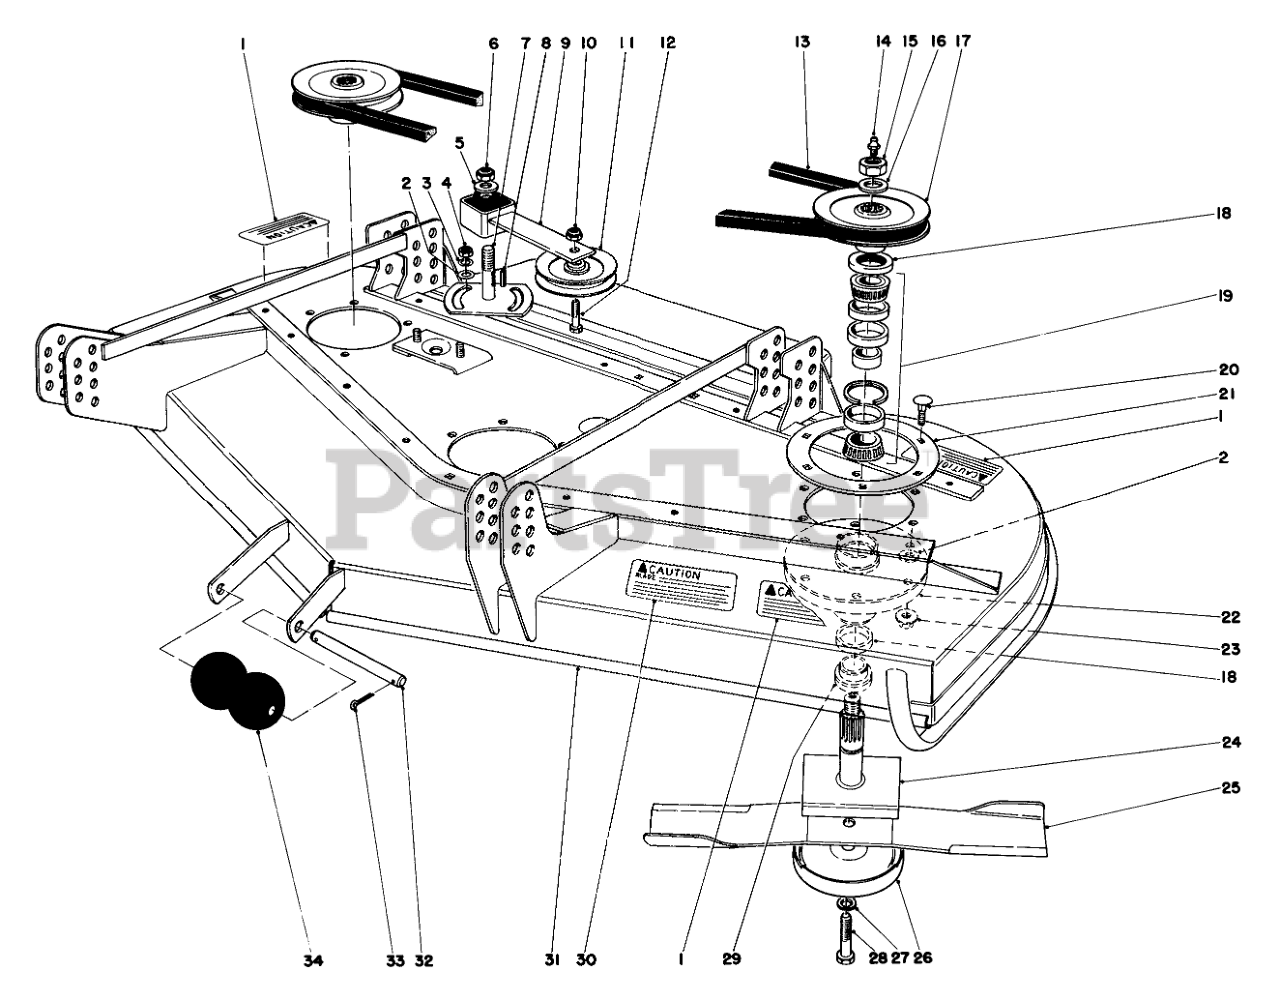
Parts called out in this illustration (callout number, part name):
1	DECAL-CAUTION, BLADE
2	WASHER-FLAT
3	WASHER-LOCK
4	NUT-JAM
5	WASHER-FLAT
6	NUT-LOCK, NI
7	PLATE-IDLER
8	KEY-SQUARE
9	IDLER ARM ASM
10	NUT-HEX
11	Pulley
12	SCREW-HH
13	V-BELT
14	FITTING-GREASE
15	NUT-HEX
16	WASHER
17	PULLEY AND HUB ASM
18	SEAL-OIL
19	BEARING ASM
20	SCREW-CARR
21	SUPPORT-DECK, RING
22	Housing-Spindle
23	NUT-HF
24	SHAFT
25	Blade
26	Cup-Scalp
27	WASHER-LOCK
28	SCREW-BLADE
29	SPACER
30	Decal-Caution
31	CUTTER DECK WA RO
32	SHAFT-ROLLER
33	PIN-COTTER
34	ROLLER
